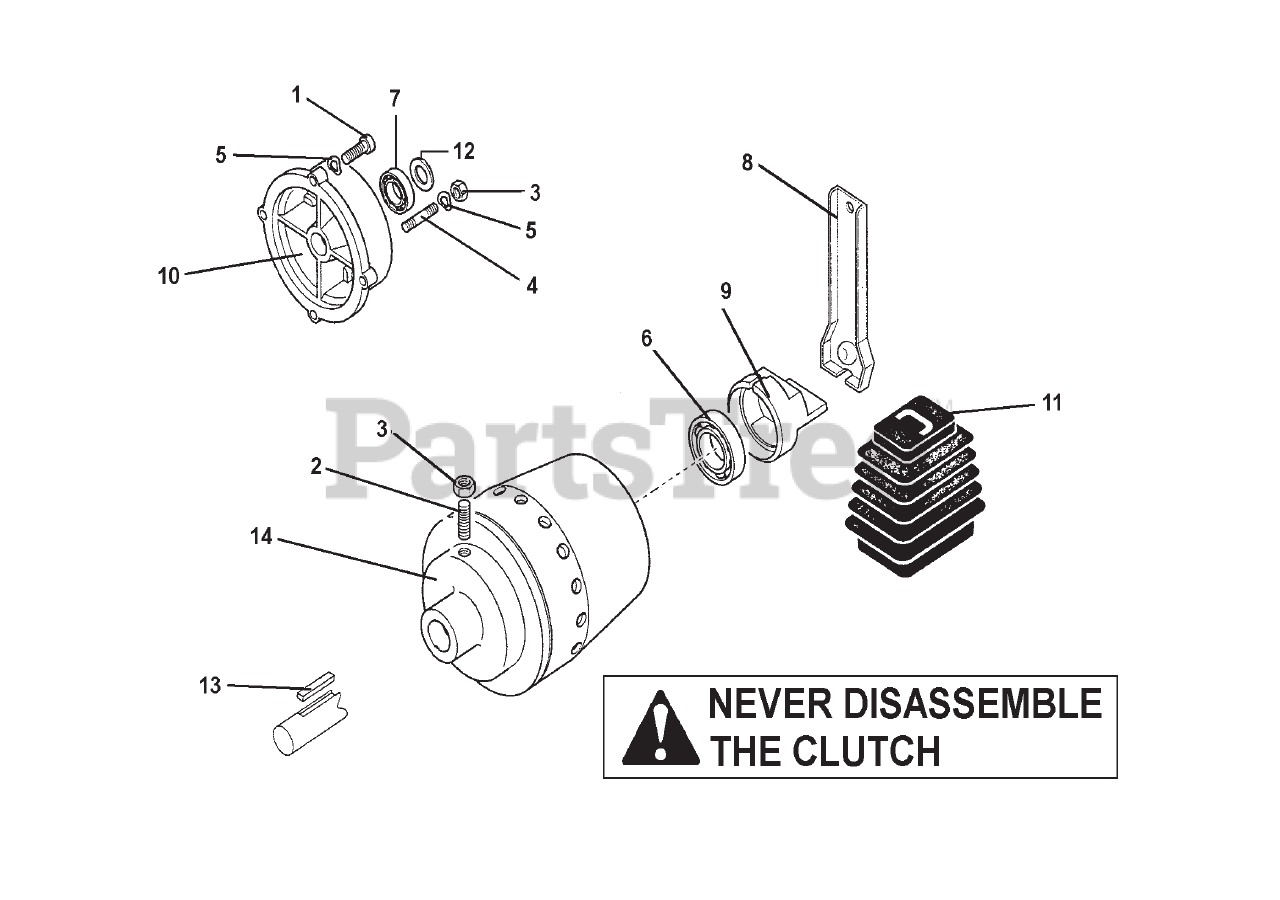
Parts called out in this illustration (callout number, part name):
1	SCREW, 5/16X7/8"
2	SCREW, M8X35
3	NUT, M8
4	STUD, M8X40X14X14
5	WASHER, WAVEY, M8
6	BEARING, M17X40X12
7	BEARING, M20X47X14
8	LEVER, RECOIL START
9	CONE PUSHER
10	FLANGE, 6.5HP INTEK & 5.5HP HONDA
12	WASHER
14	CLUTCH, 6.5HP (INCLUDE 6 & 9)
